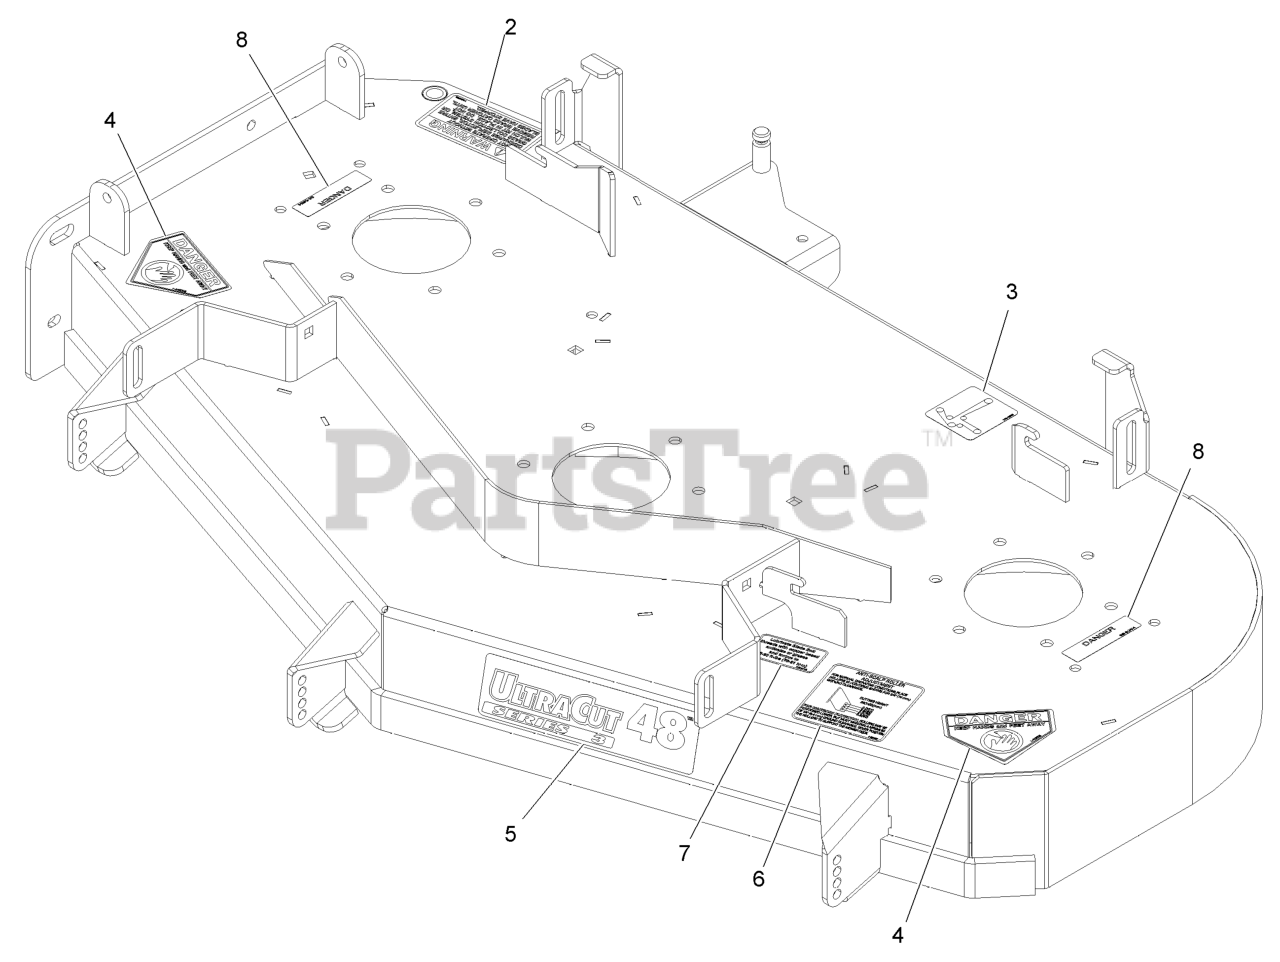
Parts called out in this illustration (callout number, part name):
2	DECAL-WARNING, DISCHARGE
3	DECAL-ROUTING, BELT
4	DECAL-DANGER
5	DECAL-ULTRACUT 48 SERIES
6	DECAL,ANTISCALP
7	DECAL,BOLT TORQUE
8	DECAL-COVER, MISSING
